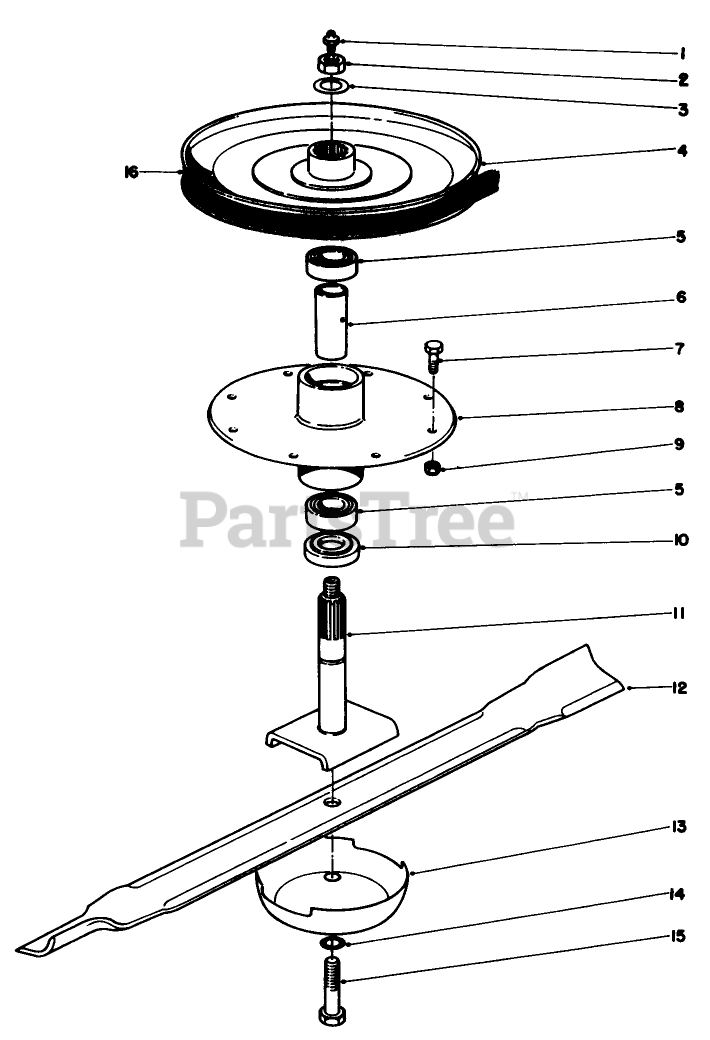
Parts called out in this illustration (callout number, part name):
1	FITTING-GREASE
2	Locknut
3	WASHER-FLAT
4	Pulley
5	BEARING-BALL
6	SPACER-BEARING
7	SCREW-HH
8	HOUSING-SPINDLE
9	NUT-LOCK, NI
10	SPACER
11	Shaft-Spindle
12	Blade
13	Cup
14	WASHER-LOCK/SP
15	SCREW-BLADE
16	V-BELT
